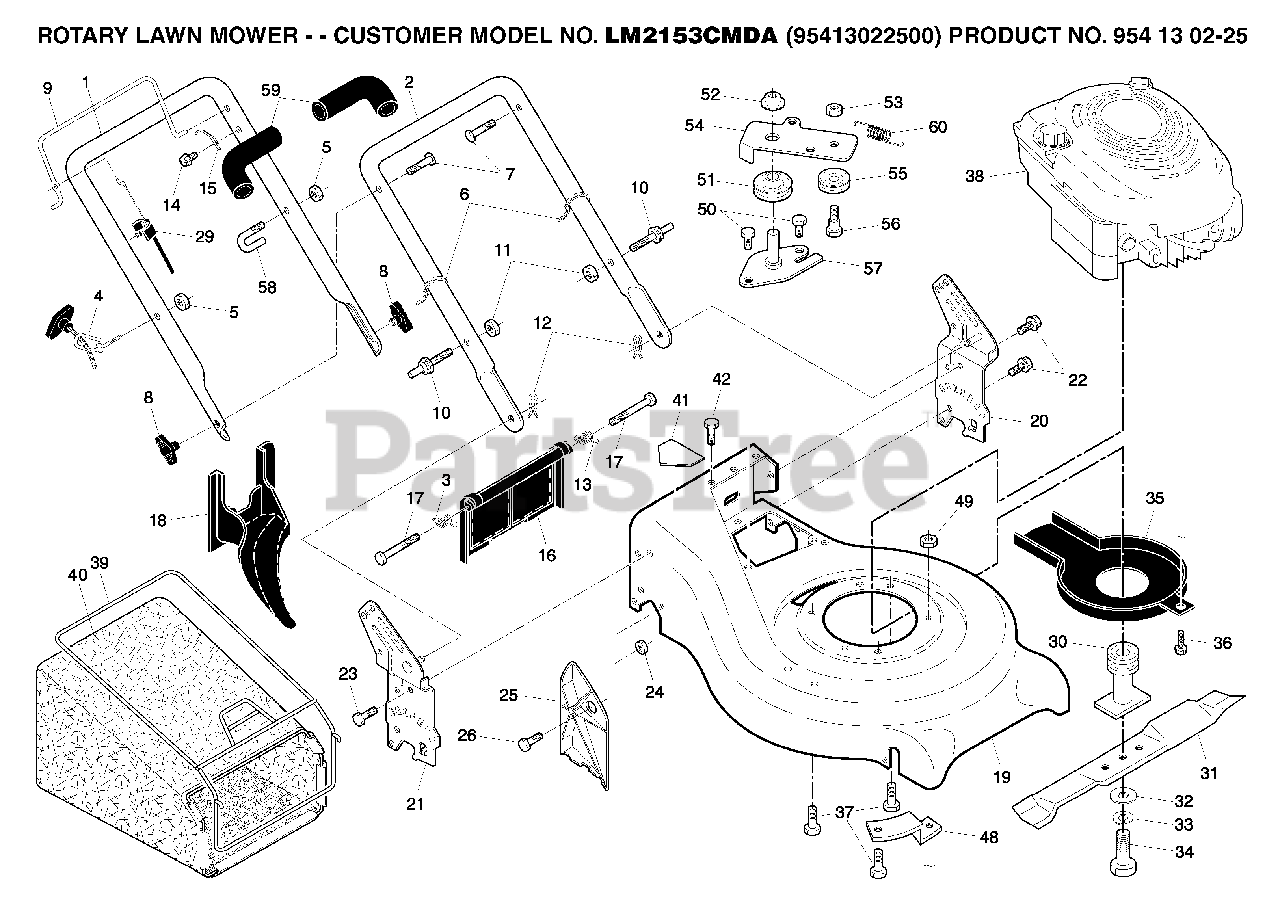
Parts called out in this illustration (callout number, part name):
2	HANDLE LOWER
3	SPRING, REAR DOOR, RH
4	ROPE, GUIDE
5	NUT
6	TIE GUIDE
7	BOLT, HANDLE 5/16-18X1.75
8	KNOB, DEFLECTOR
11	NUT.CENTERLOCK.5/16-
12	HAIRPIN COTTER
13	SPRING.LH.REAR.DOOR.21.RWGD
15	BRACKET UPSTOP
16	DOOR.REAR.PLASTIC.21.RWGD.BLAC
18	PLUG, MULCHER
20	BRKT.ASM HNDL
21	BRKT.ASM.HNDL
22	SELF-TAPPING SCREW 5/16-18X3/4
23	BOLT, HEX HEAD 5/16-18
24	NUT.71038.31-18.HEX.NYLOCK
25	CLIPPING DEFLECTOR
29	SNAP-ON.ZONE.CABLE.ASS
30	BLADE ADAPTOR / PULLEY
32	WASHER,HARDEN
33	LOCKWASHER
34	SCREW, HEX HD 3/8-24 X 1-3/8
35	DEBRIS SHEILD
36	SCREW.HEX.WSH
37	BOLT 3/8-16X1-1/8
40	GRASS CATCHER FRAME
41	DECAL.INTERNATIONL.CUTFINGER
48	BRACKET
51	PULLEY ASSY
52	HEX FLANGE LOCKNT
54	IDLER ARM
55	IDLER PULLEY
57	BRACKET ASSEMBLY
59	GRIP.HANDLE.FOAM.WIDE.(1 SIDE)
60	SPRING
